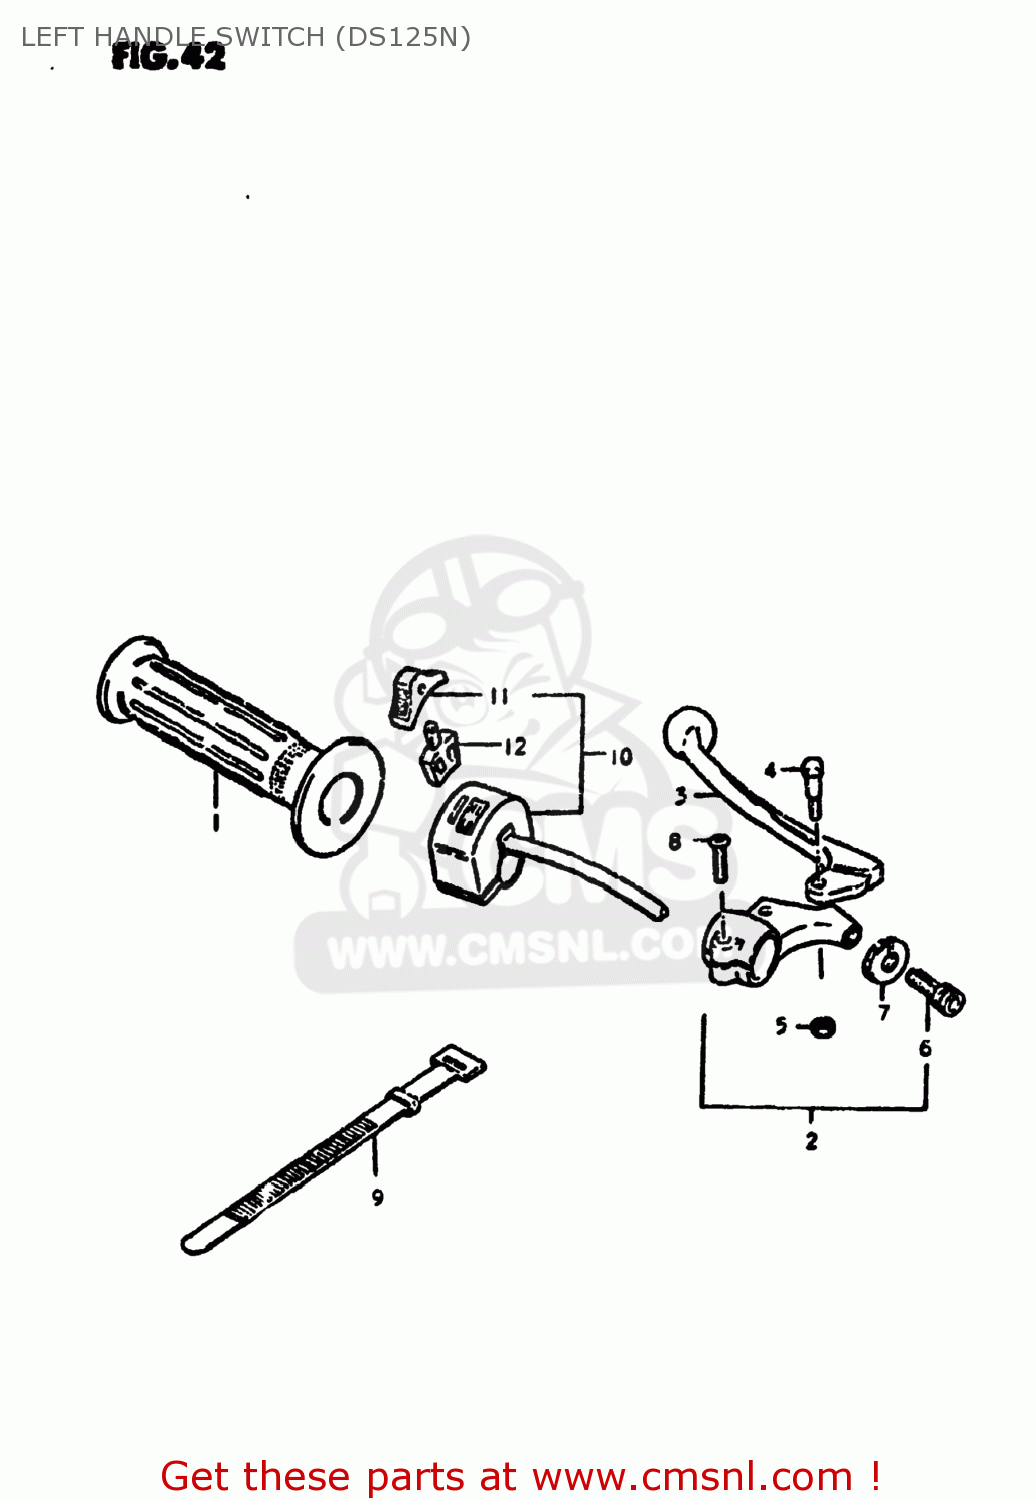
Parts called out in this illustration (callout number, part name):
1	GRIP,L
2	LEVER ASSY,CLUTCH
3	LEVER,CLUTCH
4	BOLT,LEVER
5	NUT 6MM
6	ADJUSTER,CABLE
7	NUT,CABLE ADJUSTER
8	SCREW
9	CLAMP(L:120)
10	SWITCH,DIMMER
11	KNOB,LIGHTING & DIMMER
12	BLOCK,LIGHTING/DIMMER
